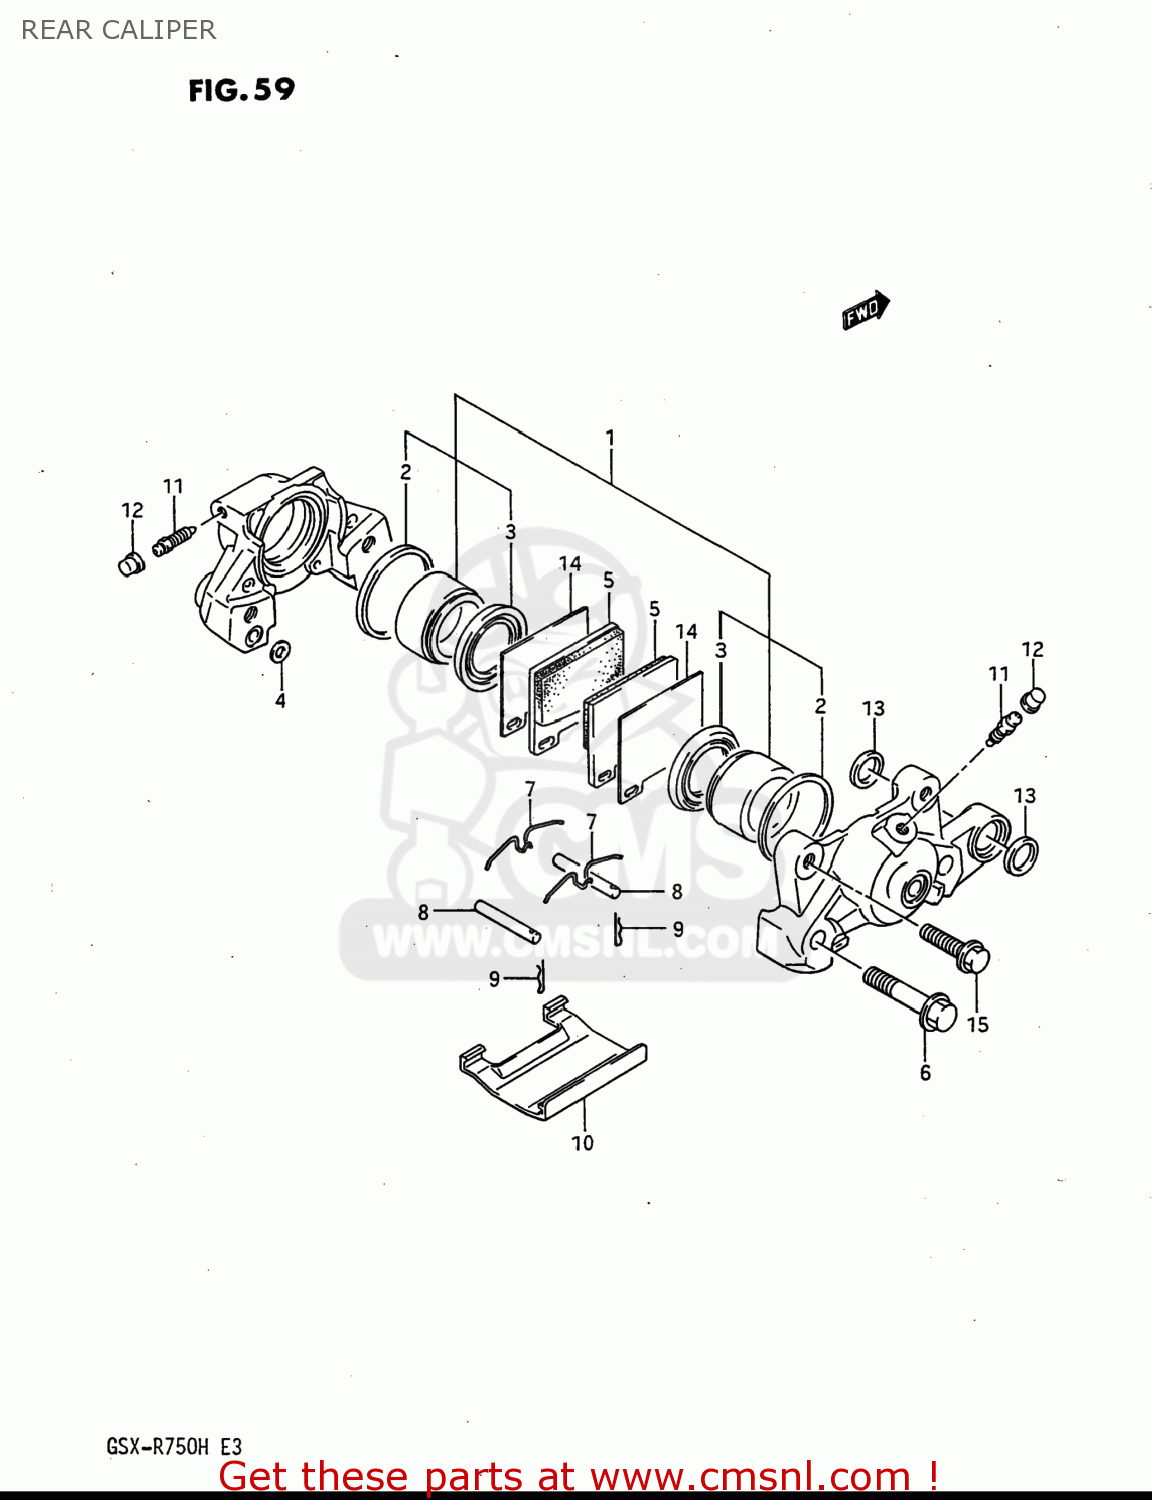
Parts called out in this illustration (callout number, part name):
1	PISTON SET
2	SEAL,PISTON
3	BOOT
4	SEAL,JOINT
5	PAD,BRAKE
6	BOLT,HOUSING
7	SPRING
8	PIN,PAD
9	CLIP,PAD PIN
10	COVER
11	BLEEDER
12	CAP,BREATHER
13	SEAL,RR CUSHION ROD LWR
14	SHIM,PAD
15	BOLT
